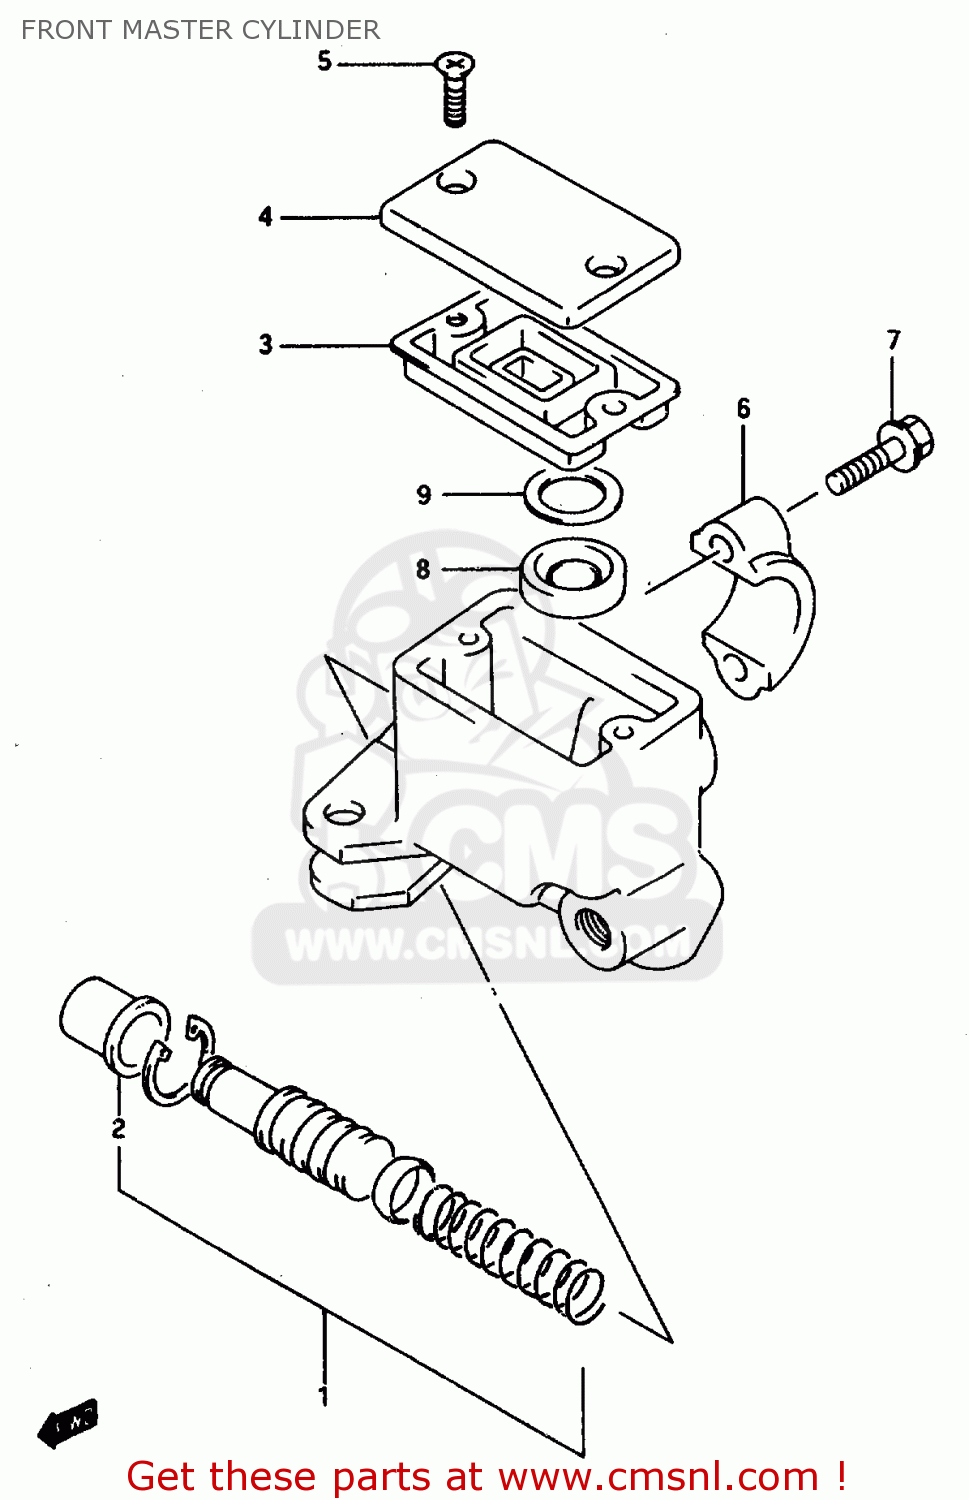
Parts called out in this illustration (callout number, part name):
1	PISTON/CUP SET
2	BOOT
3	DIAPHRAGM
4	CAP
5	SCREW
6	HOLDER
7	BOLT(6X25)
8	SEPERATOR
9	PLATE
